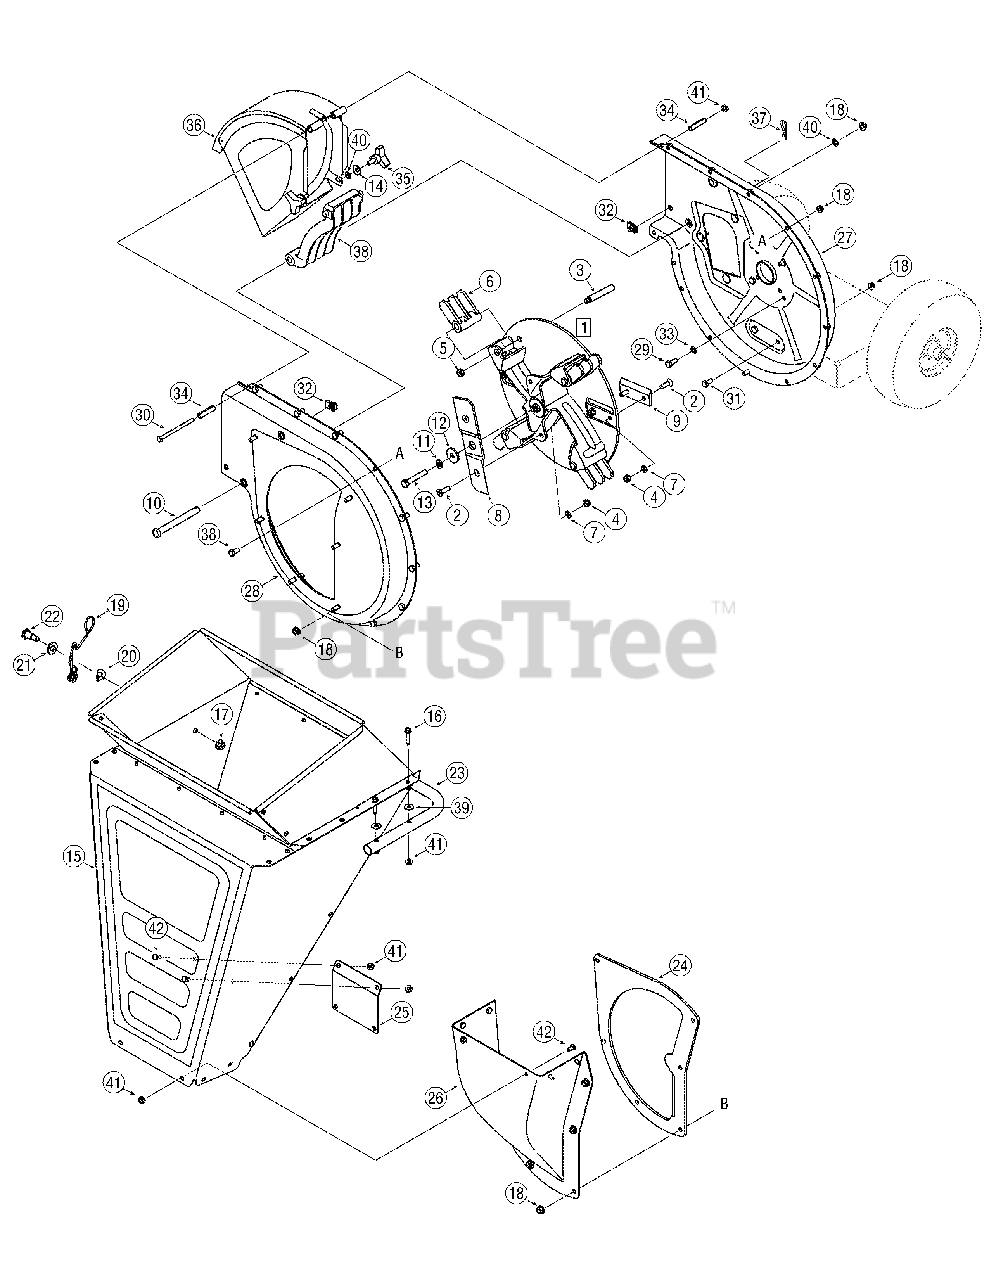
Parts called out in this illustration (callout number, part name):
1	Impeller Assembly Complete
2	Machine Screw, 5/16-24 x 1.0
3	Shoulder Pin, .5 x 2.625
4	Hex Lock Nut, 5/16-24
5	Nut, Jam Lock, 3/8-16
6	Flail Blade
7	Lock Washer, 5/16
8	Shredder Blade
9	Chipper Blade
10	Clevis Pin,.50 x 4.62
11	Lock Washer, 3/8
12	Flat Washer,.406 x 1.25
13	Hex Cap Screw, 3/8-24 x 2.2
14	Bell Washer.340 ID x.872 OD
16	Hex Cap Screw, 1/4-20 x 1.250
17	Flange Lock Nut, 3/8-16
18	Flange Lock Nut, 5/16-18
19	Torsion Spring
20	Spring Washer,.50 x 1.0 x.022
21	Flat Washer,.50 x 1.0 x.0125
22	Shoulder Screw, 3/8-16,.50 x.685
29	Hex Cap Screw, 5/16-24 x.75
30	Hex Cap Screw, 1/4-20 x 3.75
31	Hex Cap Screw, 5/16-18 x.625
32	U-Nut, 5/16-18
33	Lock Washer, 5/16
34	Hinge Spacer,.265 x.380 x 1.66
35	Knob Ass’y. (Incl. ref.# 12 & 61)
35	Knob Only, 5/16-18
37	Internal Cotter Pin
38	Shredder Screen
39	Flat Washer,.28 x.74 x.063
40	Speed Nut,.3125ID
41	Nut, Flange, Lock, 5/16-18
42	TT Screw, 1/4-20 x.5
